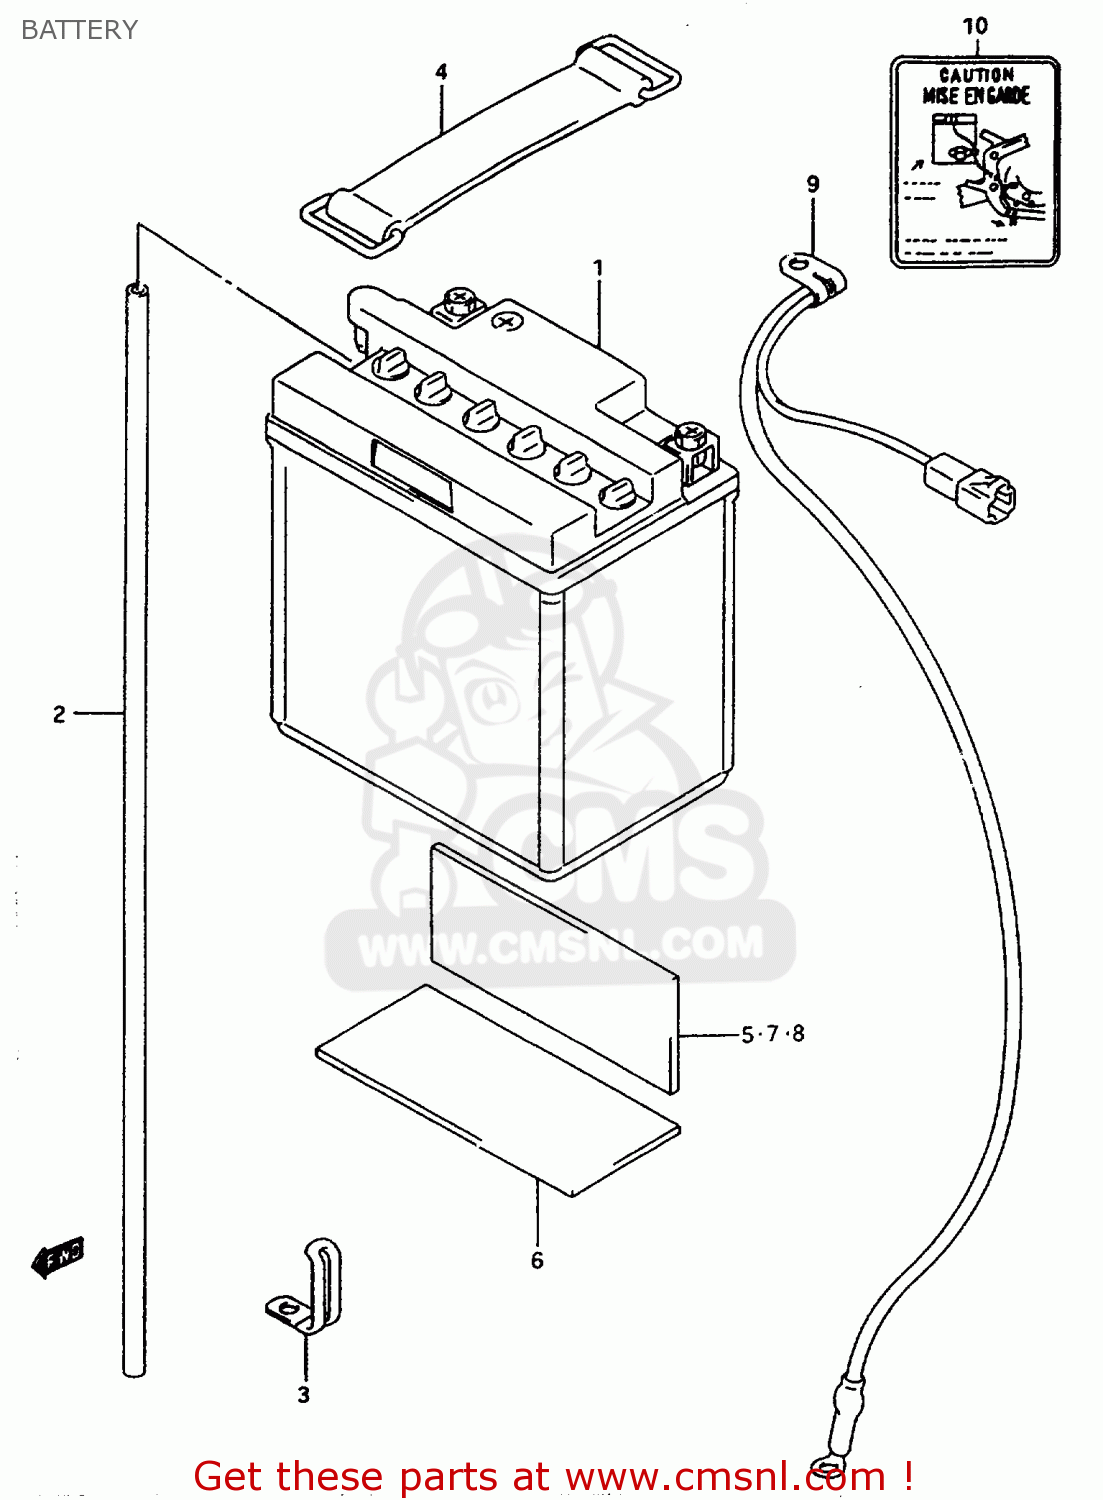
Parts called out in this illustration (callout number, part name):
1	BATTERY(YB10L-B2,12V11.6AH)
2	HOSE,BATTERY EXHAUST(L:780)
3	CLAMP(L:45)
4	BAND
5	PROTECTOR(170X95X3.0)
6	PROTECTOR(50X50X5)
7	PROTECTOR(170X95X3.0)
8	PROTECTOR(170X95X3.0)
9	WIRE,BATTERY MINUS LEAD
10	PLATE,BATTERY CAUTION
